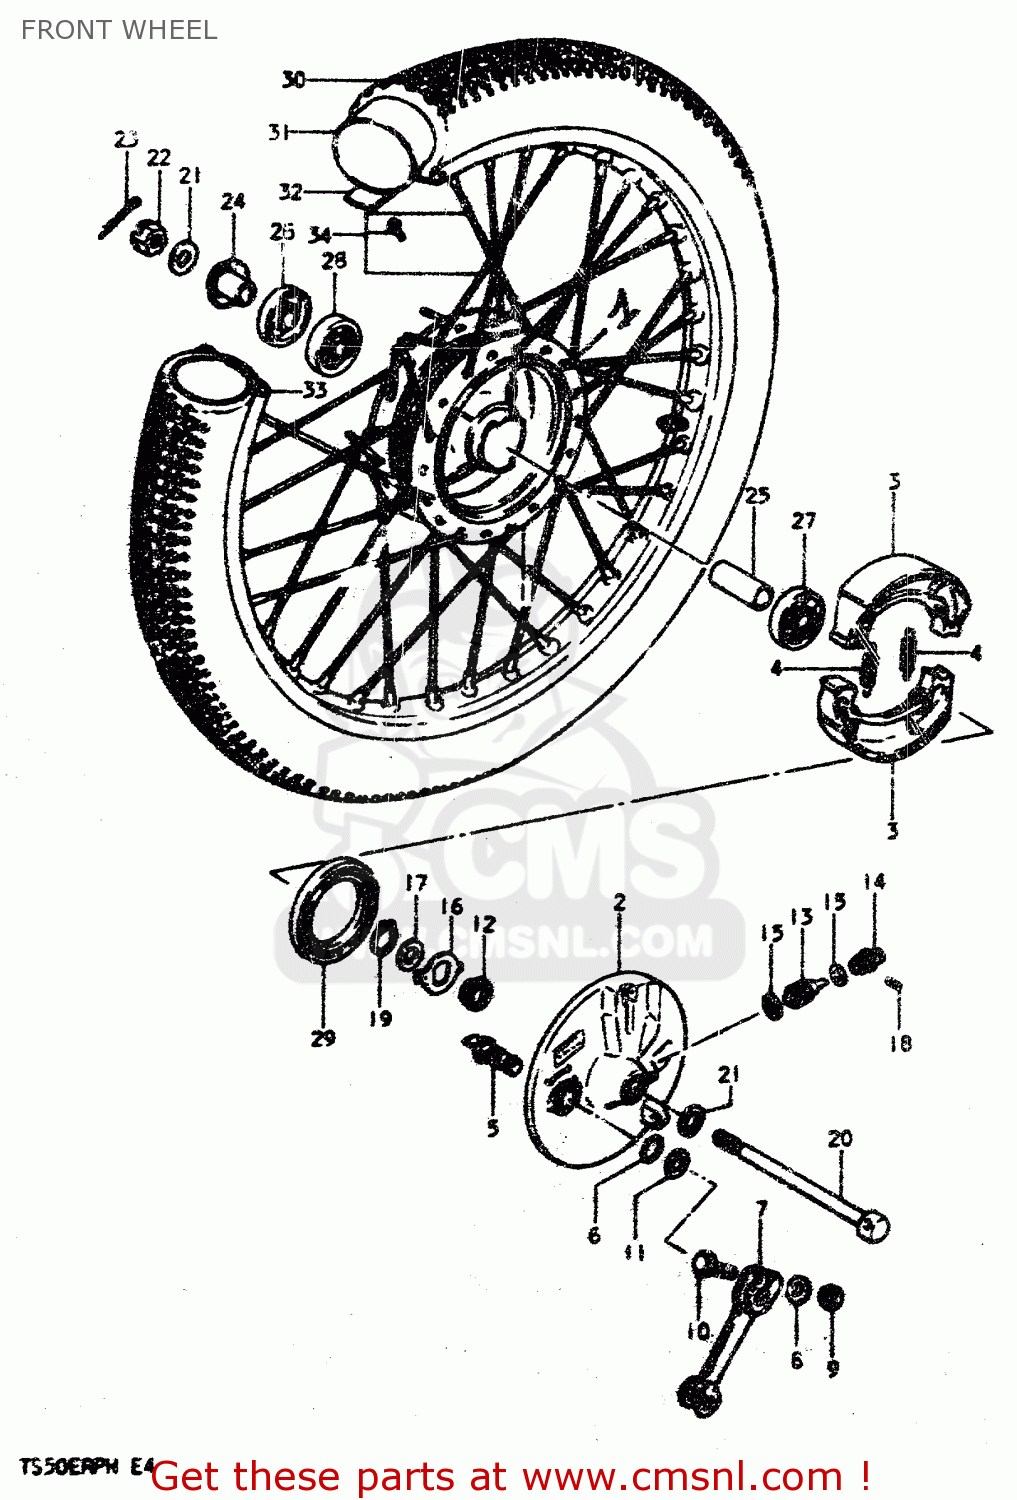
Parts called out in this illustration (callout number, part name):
1	HUB,FRONT
2	PANEL,FRONT HUB
3	SHOE,BRAKE
4	SPRING(L:34)
5	CAM,FRONT BRAKE
6	O-RING (D:2.4 ID:13.8)
7	LEVER,FR BRAKE CAM
8	WASHER
9	NUT
10	BOLT(6X33)
11	WASHER (14.5X22X1.6)
12	GEAR, SPEEDOMETER
13	PINION,SPEEDOMETER
14	BUSH,METER GEAR OUTER
15	WASHER (5.1X9X0.4)
16	DRIVER,SPEEDOMETER GEAR
17	WASHER(16X22X1)
18	SCREW
19	CIRCLIP,15MM
20	AXLE,FRONT
21	WASHER(10.5X22X2.3)
22	NUT
23	PIN 20X20
24	SPACER,FRONT AXLE,RIGHT
25	SPACER (10.2X16X51)
26	SEAL,OIL(15X31X5)
27	BEARING
28	BEARING
29	OIL SEAL (43X58X7)
30	TIRE 2.75-19 070-483MM
31	TUBE 2.75-19 070-483MM
32	PROTECTOR,WHEEL,INNER
33	RIM,FRONT WHEEL (1.40X19)
34	SPOKE SET,FRONT
